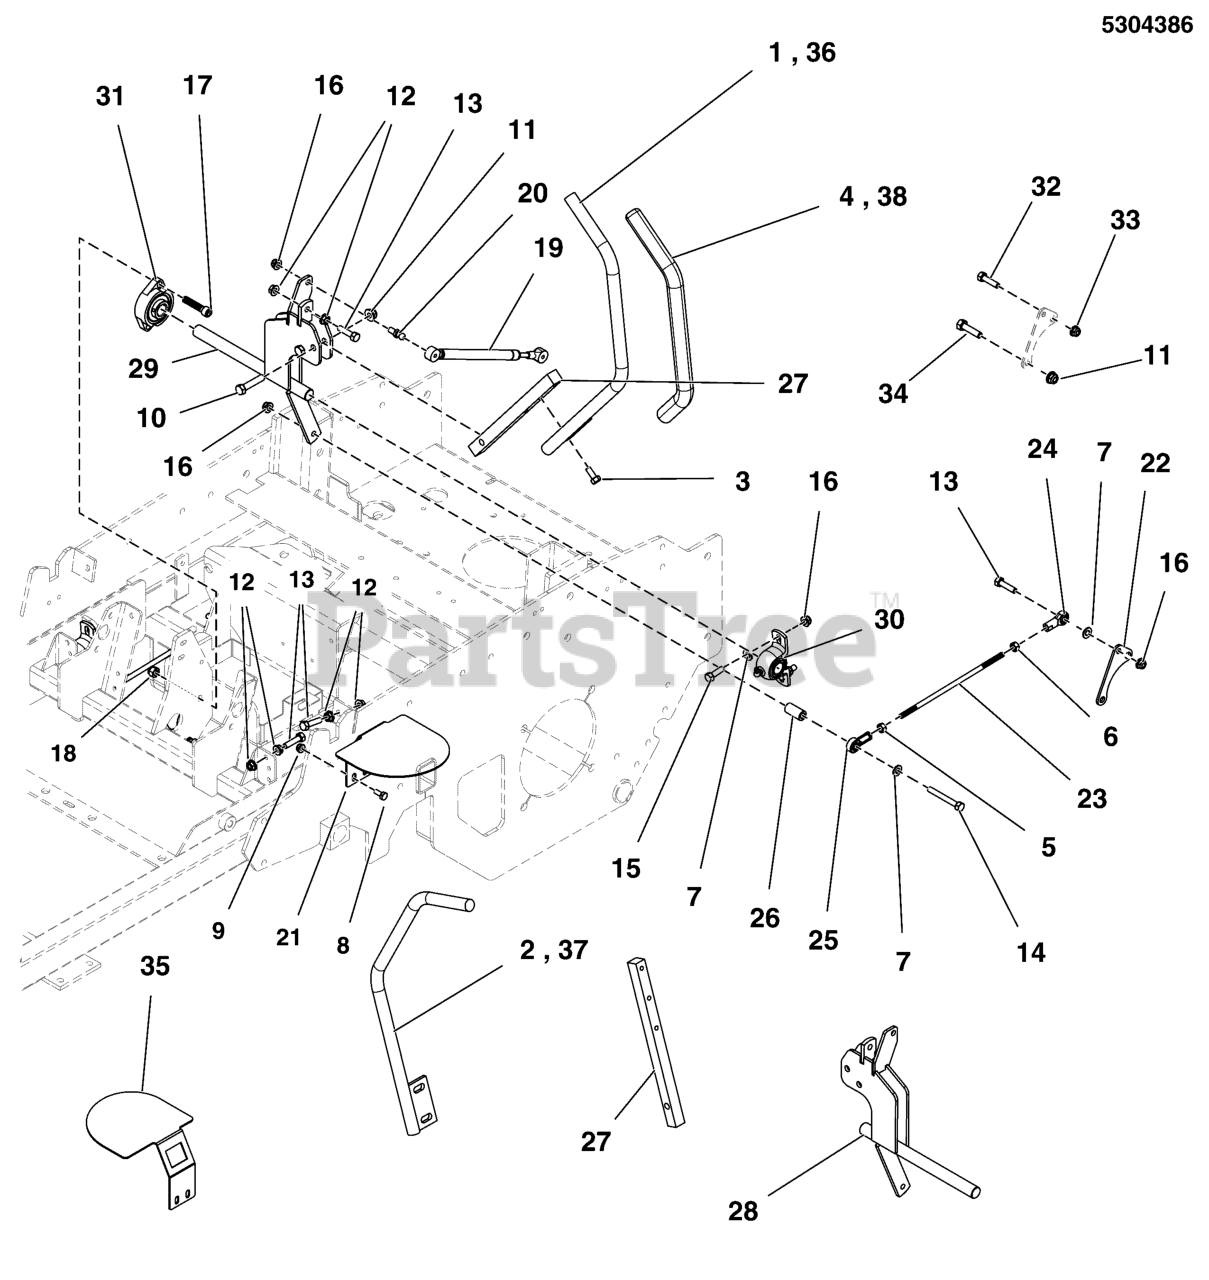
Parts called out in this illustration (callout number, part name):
1	KIT, HANDLE BAR REPLACE, L/R
2	KIT, HANDLE BAR REPLACE, L/R
3	SCREW, 5/16-18x0.750, GR5, WHIZ-LOCK, ZC
4	GRIP, FOAM, 3/4 ID, 16 LONG
5	NUT, 5/16-24 HEX
6	NUT, 5/16-24 HEX, LH
7	WASHER, 5/16" SAE
8	HHCS, 1/4-20 X 0.625, GR5, ZINC/CLEAR
9	NUT, 1/4-20 HEX NYLOCK FLANGE
10	BOLT, 3/8-16 X 1-3/4" GD5 CZ
11	NUT, 3/8-16 HEX NYLOCK FLANGE
12	NUT, 5/16-18 HEX SERRATED FLANGE (SMALL)
13	BOLT, 5/16-18 X 1-1/4 GD5 YZ
14	BOLT, 5/16-18 X 2-1/2 GD5 YZ
15	BOLT, 5/16-18 X 1 GD5 YZ
16	NUT, 5/16-18 HEX NYLOCK FLANGE
17	BOLT, 3/8-16 X 1-3/4, SHCS, YZ
18	NUT, 3/8-16 HEX NYLON LOCK
19	DAMPENER, CONTROL,#(P6709/P3610)
20	BALL STUD, 5/16 X .50,# PC-477-2)
21	PLATE, MOTION CONTROL SWITCH, F160Z LH - BLK
22	PLATE, HYDRO CONNECTOR - BLK
23	ROD, HYDRO LINKAGE
24	BALL JOINT 5/16-24 RH FEMALE STAMPED STL
25	BALL JOINT 5/16-24 LH FEMALE STAMPED STL
26	SPACER, .33 X .63 X 1.25, CZ
27	MOUNT, CONTROL ARM - BLK
28	WELD, CONTROL SHAFT, LH - BLK
29	WELD, CONTROL SHAFT, RH - BLK
30	BEARING, 3/4" PILLOW BLOCK
31	BEARING, FLANGE
32	BOLT, 7/16-14 X 3/4, GD5 YZ
33	NUT, 7/16-14 HEX TOP LOCK
34	BOLT, 3/8-16 X 3/4" GD5 CZ
35	PLATE, MOTION CONTROL SWITCH, F160Z RH - BLK
36	WELD,HANDLE MOTION CNTRL,17.0,1.0,LH,BLK
37	WELD, HANDLE MOTION CNTRL,17.0,1.0,RH,BLK
38	GRIP, FOAM, 1" ID, 16" LONG
